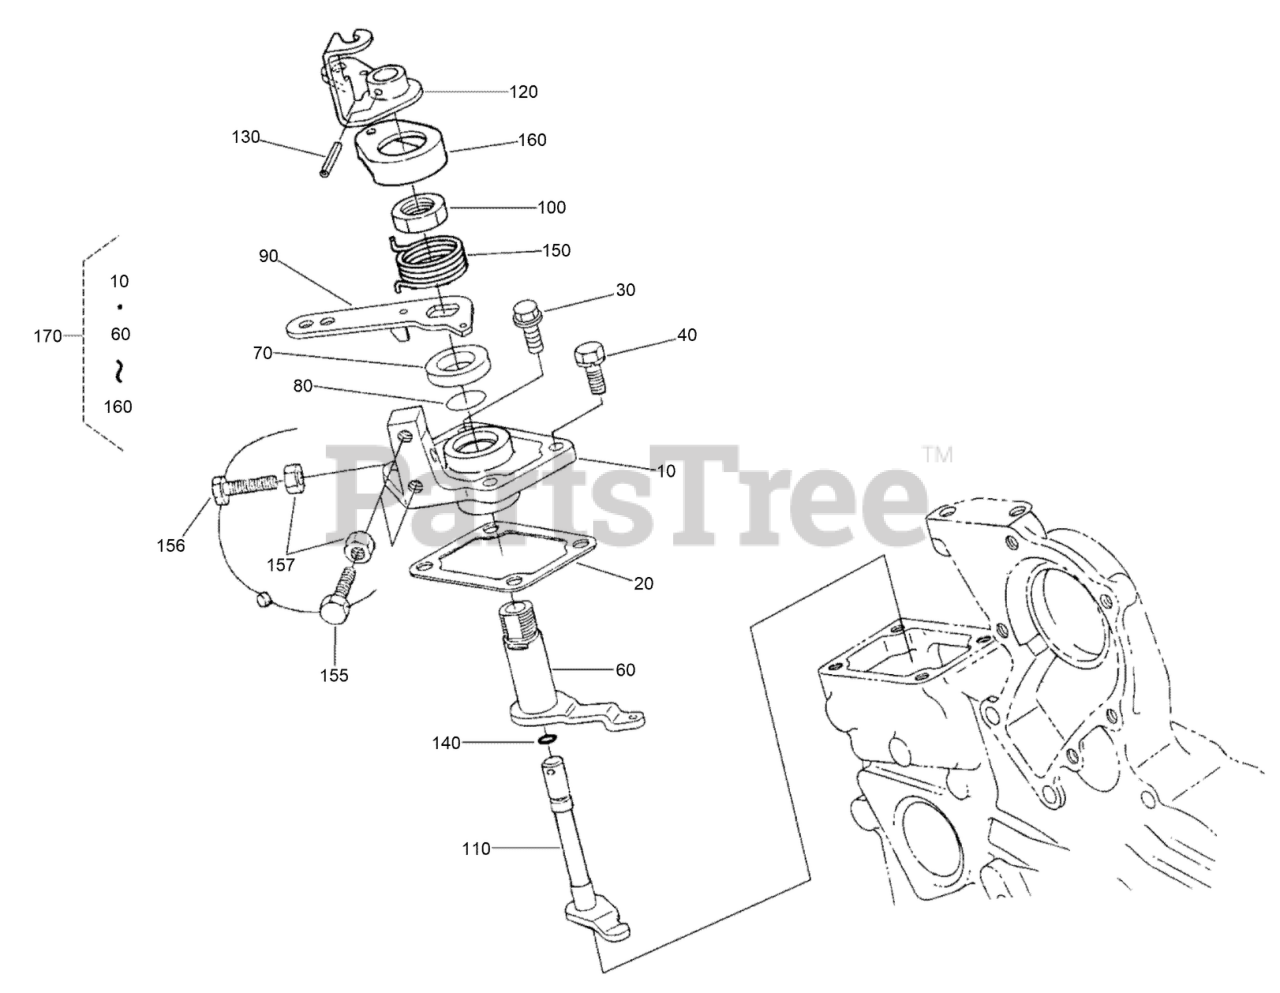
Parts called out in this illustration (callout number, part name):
10	PLATE-CONTROL, SPEED
20	GASKET-PLATE, CONTROL
30	BOLT-FLANGE
60	LEVER-GOVERNOR
70	COLLAR
80	O-RING
90	LEVER-CONTROL, SPEED
100	NUT-CONTROL, SPEED
110	SHAFT-LEVER
120	LEVER(ENGINE STOP)
130	PIN-SPRING
140	O-RING
150	SPRING-RETURN
155	SCREW-STOPPER
170	PLATE,COMP
